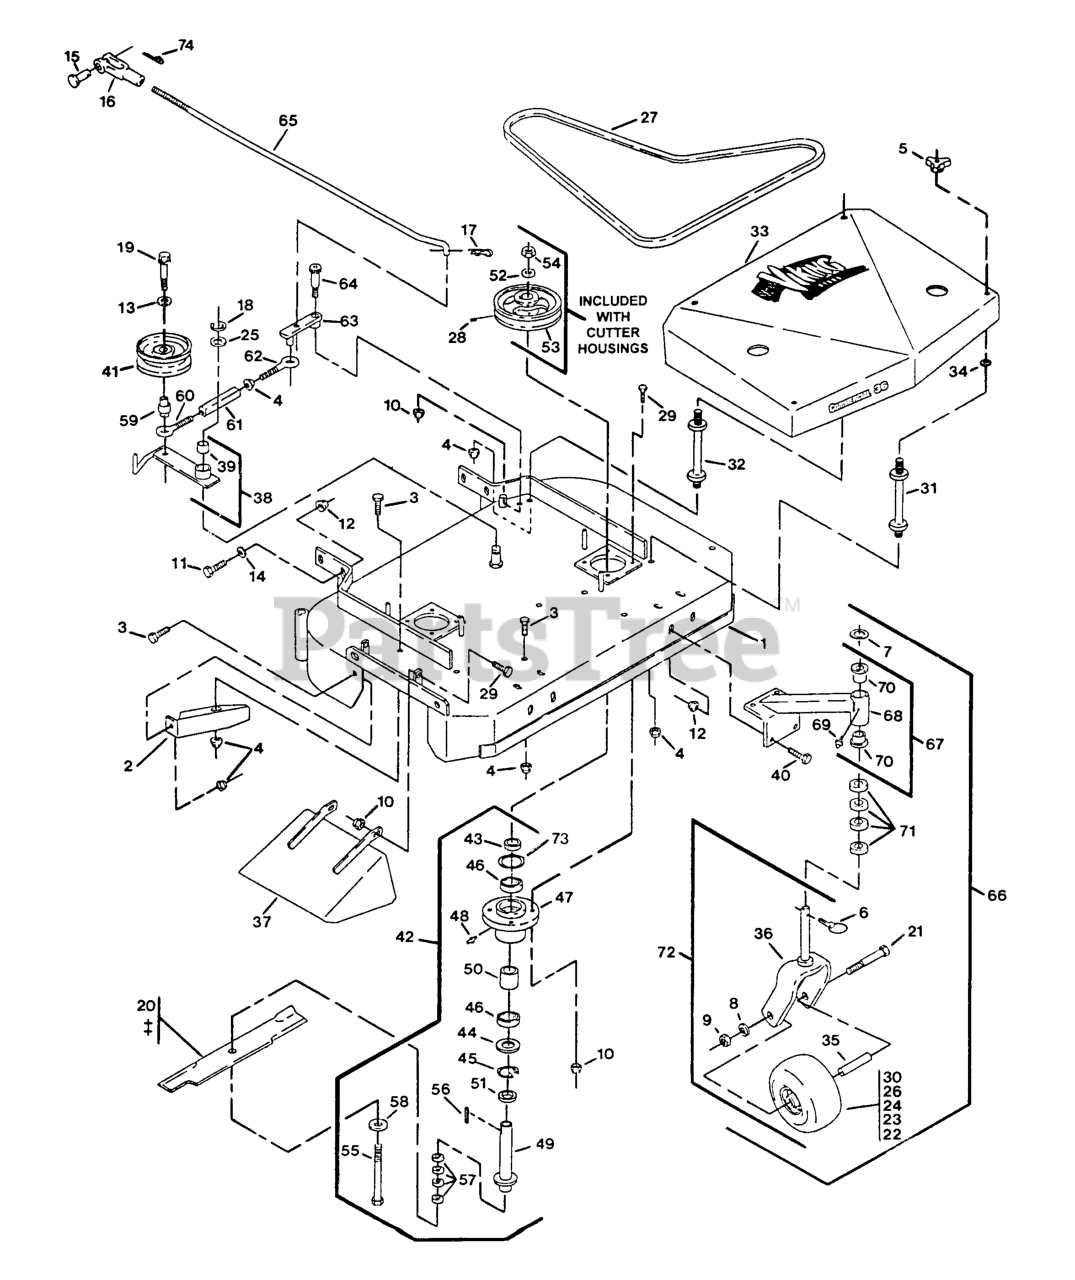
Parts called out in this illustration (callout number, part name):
2	BAFFLE-DOGLEG
5	KNOB-3 PRONG
7	WASHER-FLAT
15	PIN-CLEVIS
16	YOKE-ADJUSTABLE
17	PIN-COTTER
22	BUSHING
23	BEARING
25	WASHER-SPINDLE
27	BELT,DECK DRIVE
28	SCREW-SET
31	STUD-SHIELD, BELT (SHORT)
32	STUD-SHIELD, BELT (LONG)
39	BEARING,POWDERED METAL
42	ASM,HOUSING CUTTER
44	SEAL,DUST
45	RING,SNAP WLDS N5000-244
47	HOUSING,CUTTER
50	SPACER,BRG/BRG
51	SPACER,BEARING &SPINDLE
52	WASHER-RETAINER, SHEAVE
55	SCREW-CAP, HH
58	WASHER-SPRING
59	BUSHING-ENGAGEMENT
60	EYEBOLT-THREAD, LH
61	BODY-TURNBUCKLE
62	EYEBOLT-THREAD, RH
64	BOLT,SHLDR KSKH
65	ARM-LINKAGE, ASSIST
66	CASTER/MOUNT ASM
67	SUPPORT ASM
70	BEARING-FLANGED
71	SPACER-CASTER
